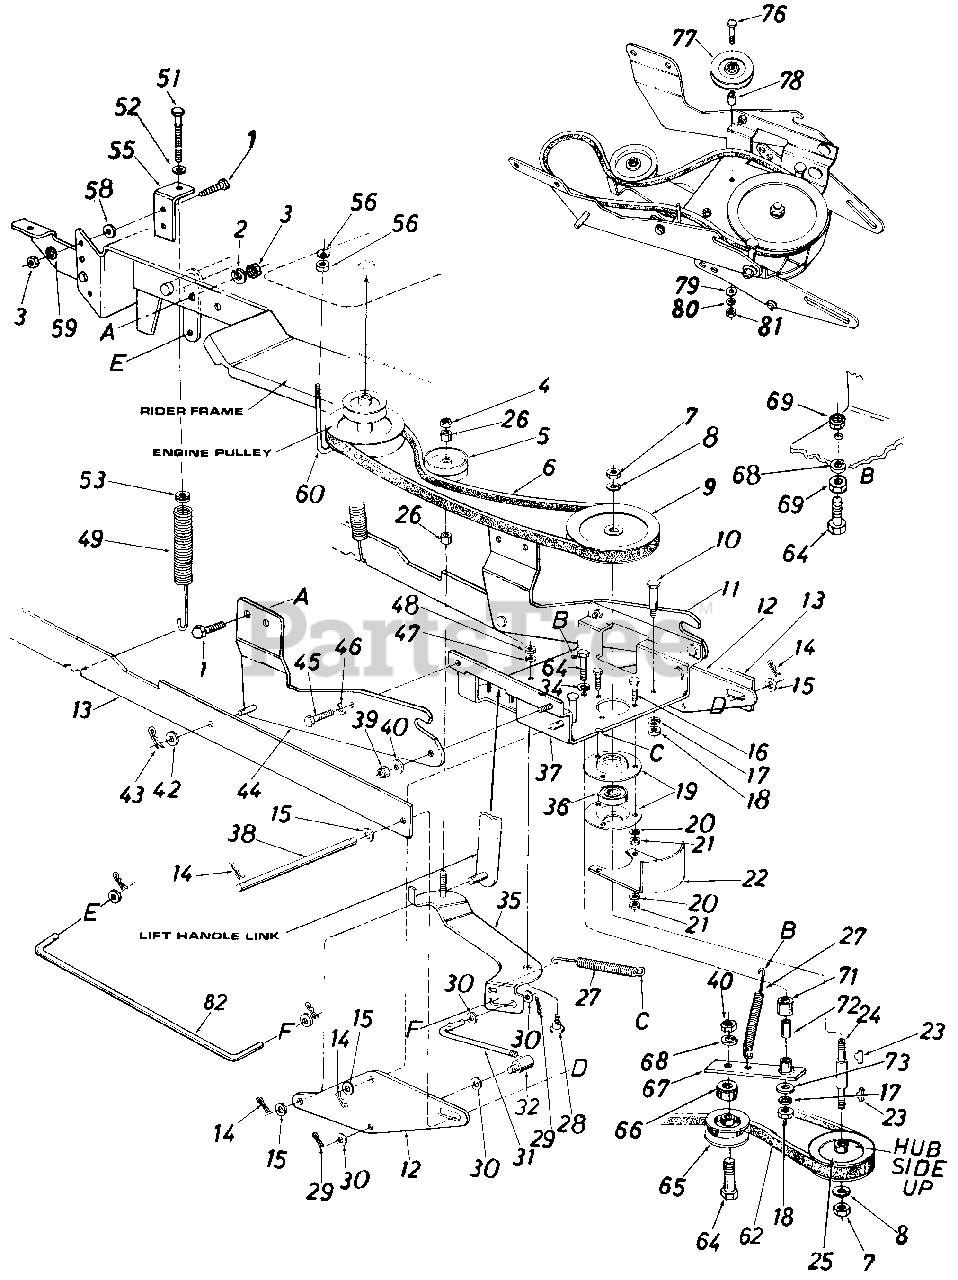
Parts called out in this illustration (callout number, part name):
1	Hex Bolt 1/4-28 x .75" Lg. Grade 5
2	L.-Wash. 1/4" I.D.*
3	Hex Nut 1/4-28 Thd.*
4	Hex Cent. L-Nut 3/8-16 Thd.
5	Idler Pulley
6	"V"-Belt 1/2 x 49" Lg.
7	Hex Jam Nut 5/8-11 Thd.
8	L-Wash 5/8" I.D.*
9	6.50" O.D. x 5/8 Pulley
10	Shoulder Bolt
11	Channel Supporting Brkt.-R.H.
12	Linkage Brkt.
13	Linkage Arm Ass'y.
14	Intern. Cotter Pin .50 Dia.*
16	Hex Bolt 5/16 x 1.25"-Lg.
17	L.-Wash. 3/8" I.D.*
18	Hex Jam Nut 3/8-16 Thd.
19	Bearing Housing
20	L.-Wash. 5/16" I . D. *
21	Hex Nut 5/16-18 Thd.*
24	Pulley Spindle
25	5/8 Pulley-6.28 I.D. x 5.56 O. D.
26	Spacer .381 3. D. x .503 O.D. x .562 Lg.
27	Extension Spring .54O.D. x-5.25"
28	Shoulder Bolt
29	Cotter Pin 3/32" Dia. x 1.0"*
31	Control Rod
32	Ferrule
34	Hex Sems Scr. 5/16-18 x . 75" Lg . *
35	Clutch Idler Brkt. Assly.
36	Ball Bearing
37	Channel Ass'y.
38	Lift Handle Shaft
39	Hex Jam Nut 3/8-16 Thd.
40	L.-Wash. 3/8" I.D.*
43	Intern. Cotter Pin .50" Dia.*
44	Channel Supporting Brkt.-L.H.
45	Hex Bolt 3/8-16 x x 1.0" Lg. *
46	L.-Wash, 3/8" I.D.*
47	L.-Wash. 5/16" I.D.*
48	Hex Nut 5/16-18 Thd.*
49	Helper Spring
51	Hex Scr. 5/16-18 x 2.0" Lg. Special
52	Bell Wash. .345 I.D. x .88 O.D. x .06
53	Spring Insert
58	Fl.-Wash. .264" I.D.
59	L.-Wash. 1/4" I.D.*
60	J-Bolt 5/16-18 Thd.
62	"V"-Belt 1/2 "A" x .89" Lg.
64	Hex Bolt 3/8-16 x 2.0" Lg. *
65	Idler Pulley
66	Spacer .385 I.D. x .503 O.D. x .562" Lg.
67	Idler Arm Ass'y.
68	L.-Wash. 3/8" I.D.*
69	Hex Jam Nut 3/8-16 Thd.
71	Spacer .380" I.D. x 1.0" O.D.
72	Spacer .3775 I.D. x .60 O.D. x 8.3 Lg.
73	Fl.-Wash. 3/8 I.D. x 1" O.D x 1.27
76	Hex Bolt 3/8-16 x 2.5" Lg. (Grade 5)
77	Idler Pulley .38 I.D. x-3.06 O.D.
78	Spacer .385 I. D. x .630 O.D. x .76 Lg.
79	Fl.-Wash. .39 I.D. x 1-3/4 O.D. x 3/16"
80	L-Wash. 3/8" I.D.*
81	Hex Nut 3/8-16 Thd.*
